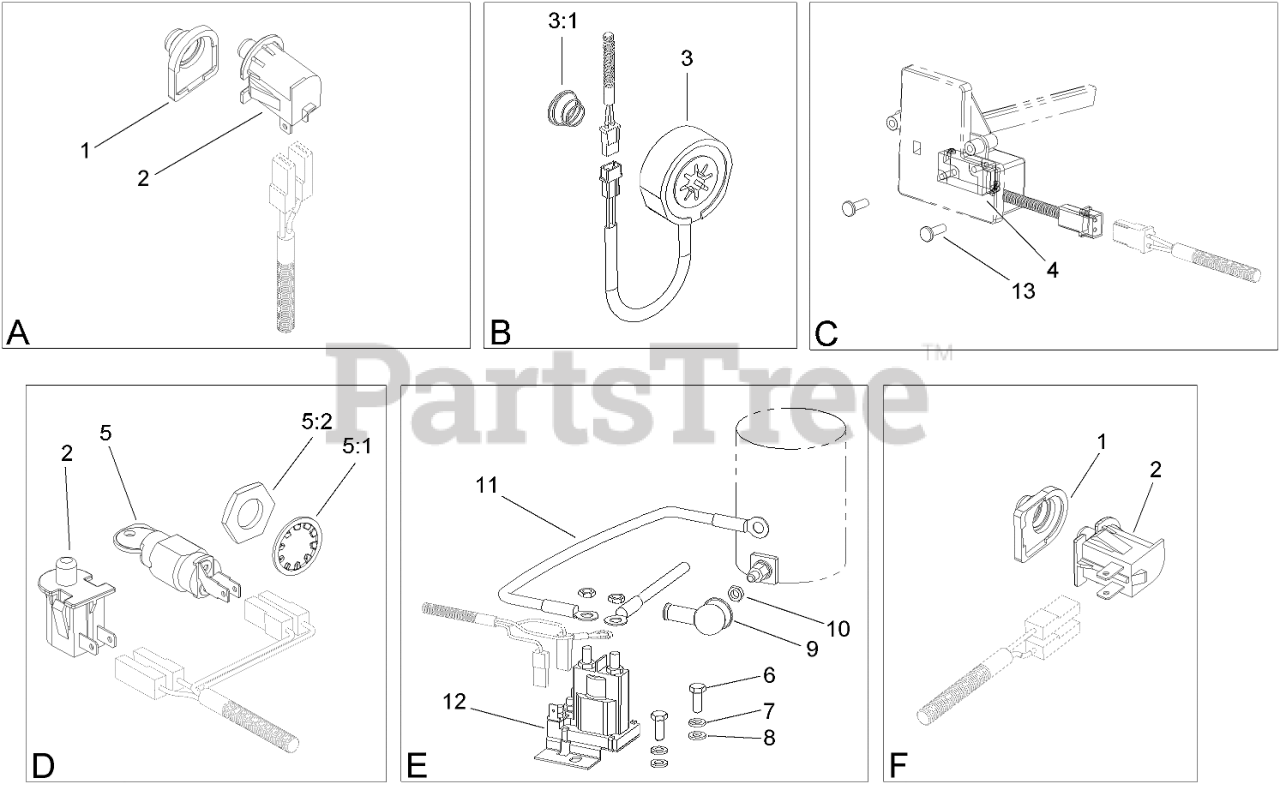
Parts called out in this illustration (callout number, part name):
1	COVER-PROTECTIVE
2	SWITCH-DELTA
3	MAGNET ASM
3:1	SPRING-COMPRESSION
4	SWITCH-OMRON
5	STARTER SWITCH ASM
5:1	WASHER-TOOTH, INTERNAL
5:2	NUT-HH
6	SCREW-HH
7	WASHER-SPRING
8	WASHER-FLAT
9	NUT-HHF
10	BOOT-RUBBER
11	LEAD-STARTER, ELECTRIC
12	Solenoid
13	Screw
